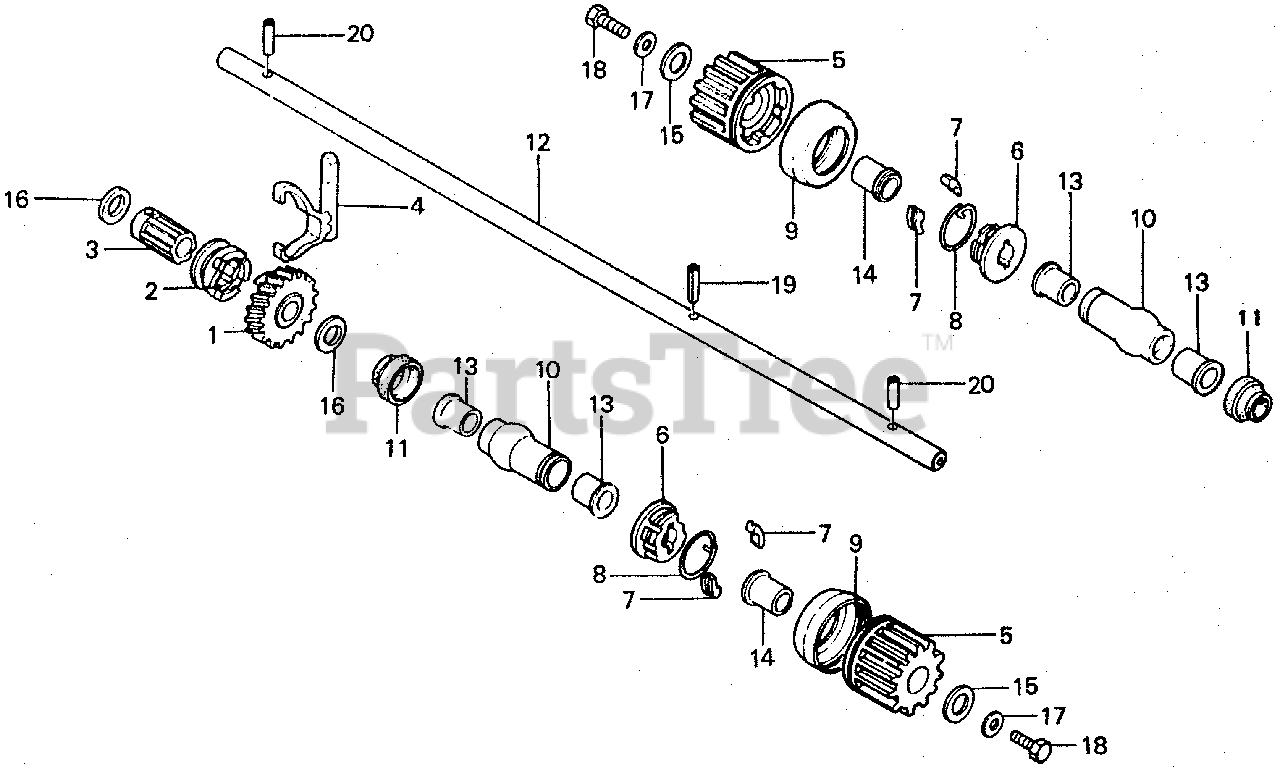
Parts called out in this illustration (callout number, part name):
1	GEAR, DRIVEN
2	CLUTCH, DRIVEN
3	SHAFT, CLUTCH
4	SHAFT, SHIFT
5	GEAR, PINION (NOT AVAILABLE)
6	HOLDER, RATCHET (NOT AVAILABLE)
8	SPRING, RATCHET RETURN
9	CAP, PINION GEAR (NOT AVAILABLE)
10	BOSS, PIPE
11	DUST SEAL (NOT AVAILABLE)
12	DRIVESHAFT (NOT AVAILABLE)
13	BUSH, DRIVESHAFT (NOT AVAILABLE)
14	BUSH, PINION GEAR
15	WASHER (12MM)
16	WASHER, THRUST (12MM)
17	WASHER, SPARK ADVANCER SETTING
18	BOLT, HEX. (6X12)
19	PIN, SPRING (5X18)
20	ROLLER (4X17.8)
